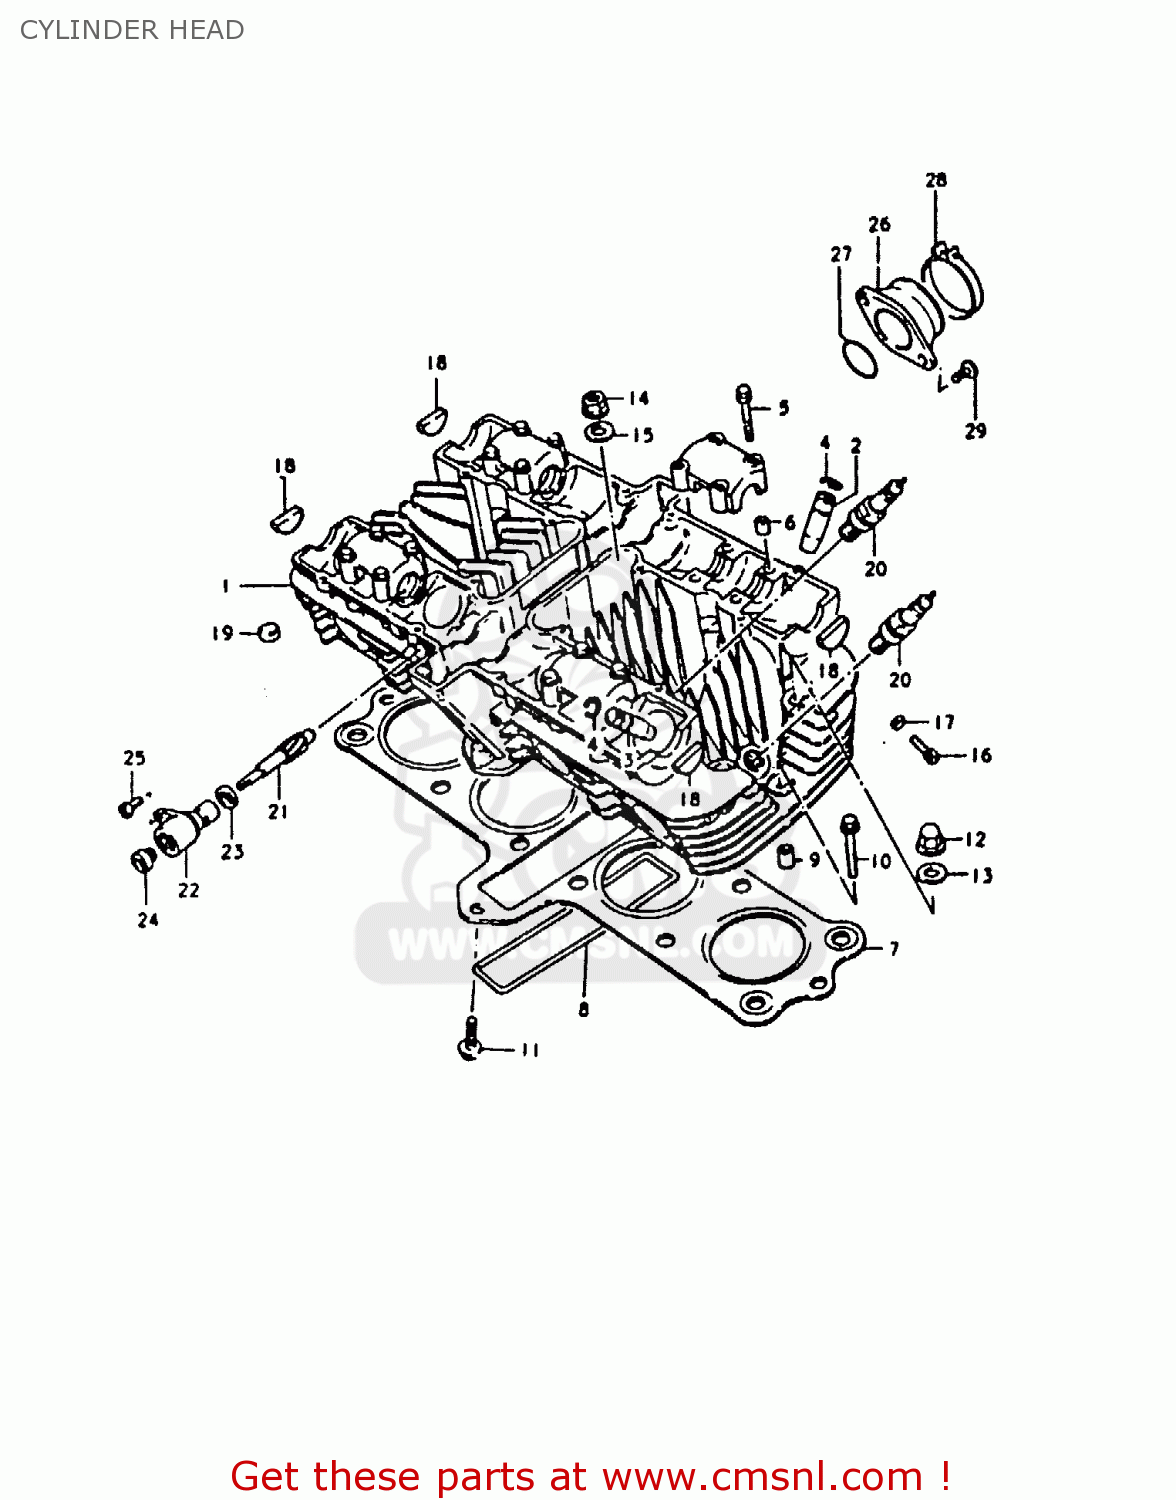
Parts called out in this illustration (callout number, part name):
1	HEAD ASSEMBLY,CYLINDER
2	GUIDE,INTAKE VALVE
3	GUIDE,EXHAUST VALVE
4	RING,SNAP
5	BOLT(6X39)
6	PIN(6.2X8X11)
7	GASKET,CYLINDER HEAD (MCA)
8	O RING(D:3,ID:26X157)
9	PIN
10	BOLT,UNDER
11	BOLT
12	NUT
13	GASKET (NAS)
14	NUT
15	WASHER(10.5X22X2.3)
16	BOLT
17	GASKET(5.3X9.3X1.2) (NAS)
18	PLUG
19	PAD
20	SPARK PLUG
21	GEAR,TACHOMETER DRIVEN
22	SLEEVE,TACHOMETER DRIVE GEAR
23	SEAL,TACHOMETER DRIVEN
24	SEAL,OIL(5X12X8)
25	SCREW(5X12)
26	PIPE,INTAKE
27	O-RING (D:2.4 ID:39.7)
28	CLAMP
29	SCREW
